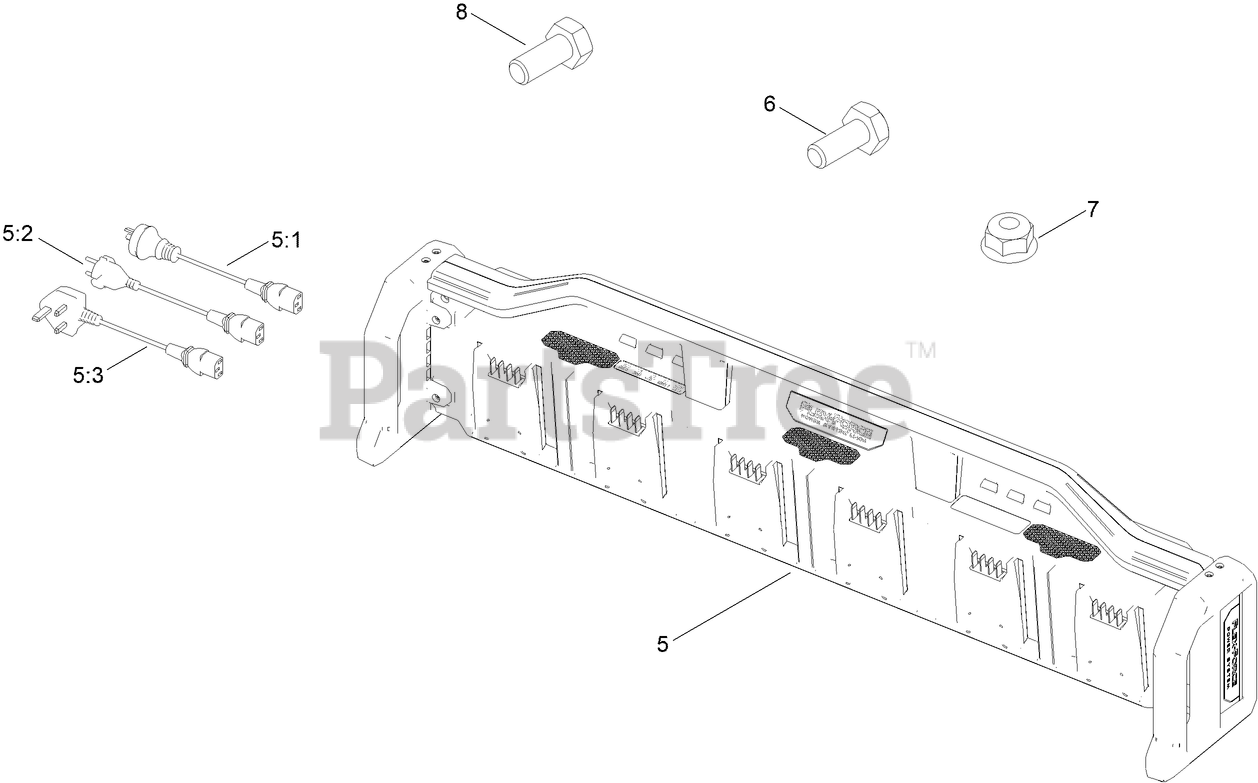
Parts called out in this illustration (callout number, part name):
5	CHARGER-BATTERY, SIX POD 60V 12 AMP CE
5:1	CORD-CHARGER, SIX POD, AU/NZ
5:2	CORD-CHARGER, SIX POD, CE
5:3	CORD-CHARGER, SIX POD, UK
6	SCREW-HH
7	NUT-FLANGE, NI
8	SCREW-HH
